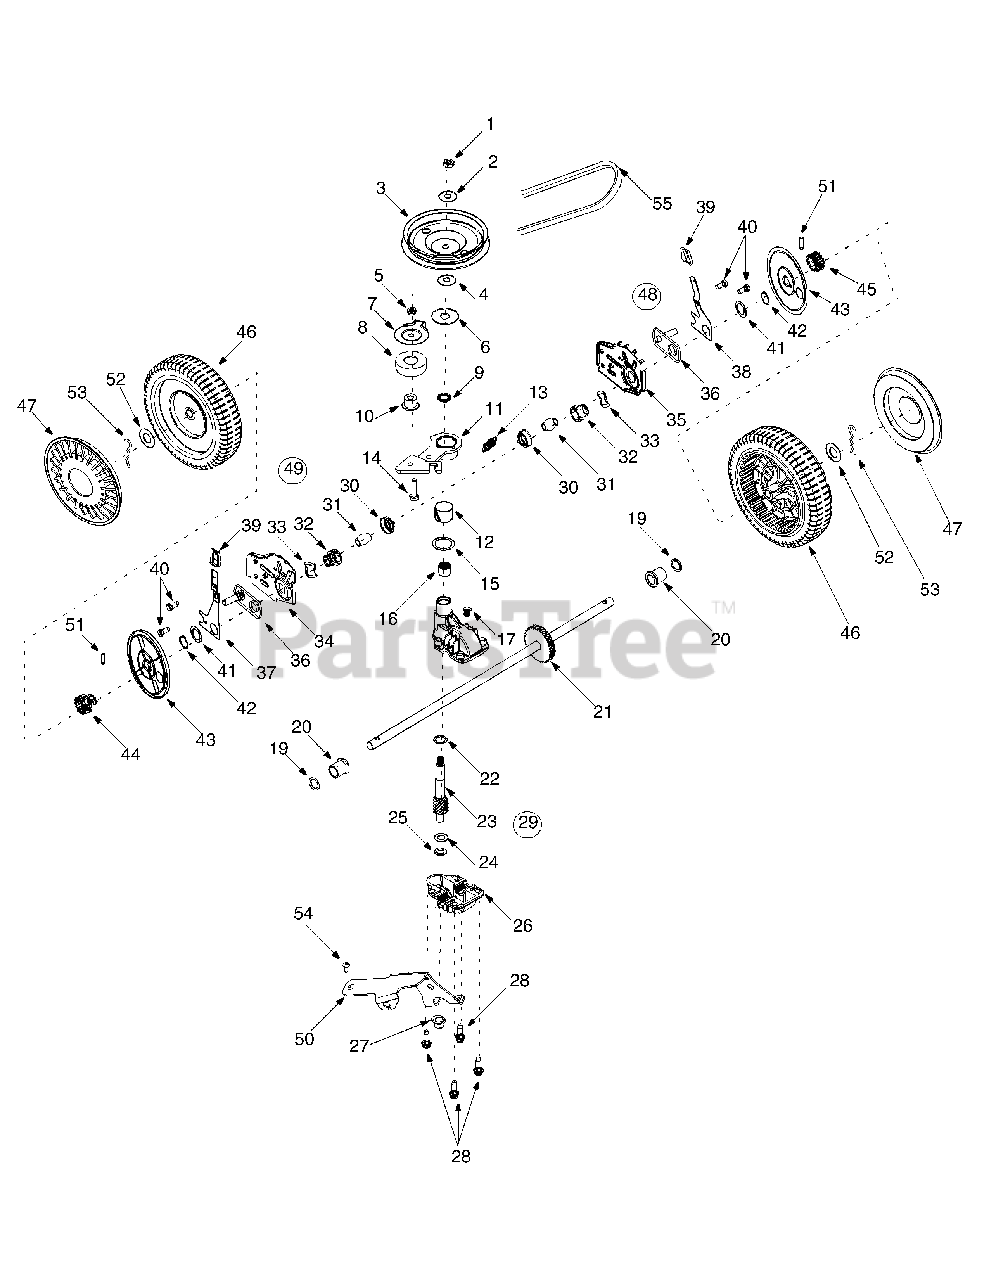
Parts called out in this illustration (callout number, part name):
1	Hex Jam Nut 5/16-24
2	Bell Washer .325 x .930 x .045
3	Pulley, 3.82 x .313 x .68
4	Bell Washer .325 x .930 x .045
5	Lock Nut 1/4-28
6	Flat Washer .442 x 1.38 x .060
7	Belt Keeper
8	Ball Bearing
9	Oil Seal
10	Flange Spacer
11	Idler Bracket Assembly
12	Bearing Sleeve
13	Extension Spring
14	Hex Cap Screw 1/4-28 x 1.00
15	Flat Washer .865 x 1.145 x .030
16	Needle Bearing .438 x .625 x .500
17	Plug 1/4 x .437
18	Upper Housing
19	Oil Seal .500 x .687 x .094
20	Flange Bearing
21	Output Shaft
22	Flat Washer .504 x .700 x .030
23	Pinion Shaft 10T
24	Thrust Washer .375 x .70 x .030
25	Thrust Washer .388 x .625 x .062
26	Lower Housing
27	Flange Bearing .378 x .531 x .370
28	Hex Screw w/Washer 1/4-20 x .750
29	Transmission Assembly
30	Bearing Retainer
31	Bearing Sleeve .50 I.D.
32	Bearing Support
33	Wave Washer 1.5 x 1.0 x .029
37	RH Front Lever
38	LH Front Lever
39	Knob
40	Hex Cap Screw 3/8-16 x .75
41	Washer DD 1.5" O.D.
42	Snap Ring
43	Wheel Dust Cap
44	Gear 14T RH
45	Gear 14T LH
46	Wheel, 8x2 Grey
47	Hubcap: EuroGray
48	RH Height Adj. Complete
49	LH Height Adj. Complete
50	Cable Idler Bracket
51	Dowel Pin
52	Flat Washer 1/2 x 1.00 x .063
53	Cotter Pin .08 x 1.42
54	Screw
55	Belt
